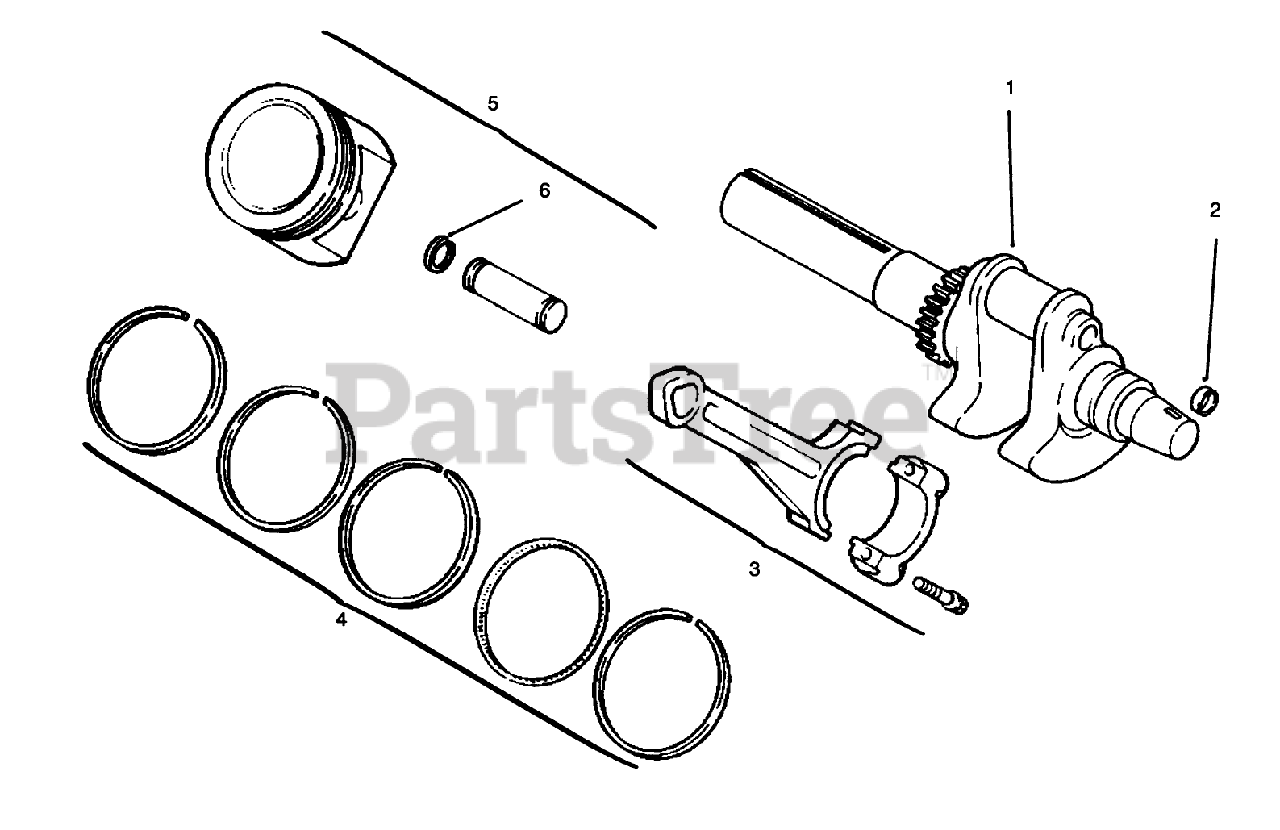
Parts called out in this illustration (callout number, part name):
1	Crankshaft
2	Plug
3	Connecting Rod STD
4	Set-Ring (Std)
5	Piston w/Ring Set (Std.) (Incl. Ref. # 4-6)
6	Retainer-Piston Pin
